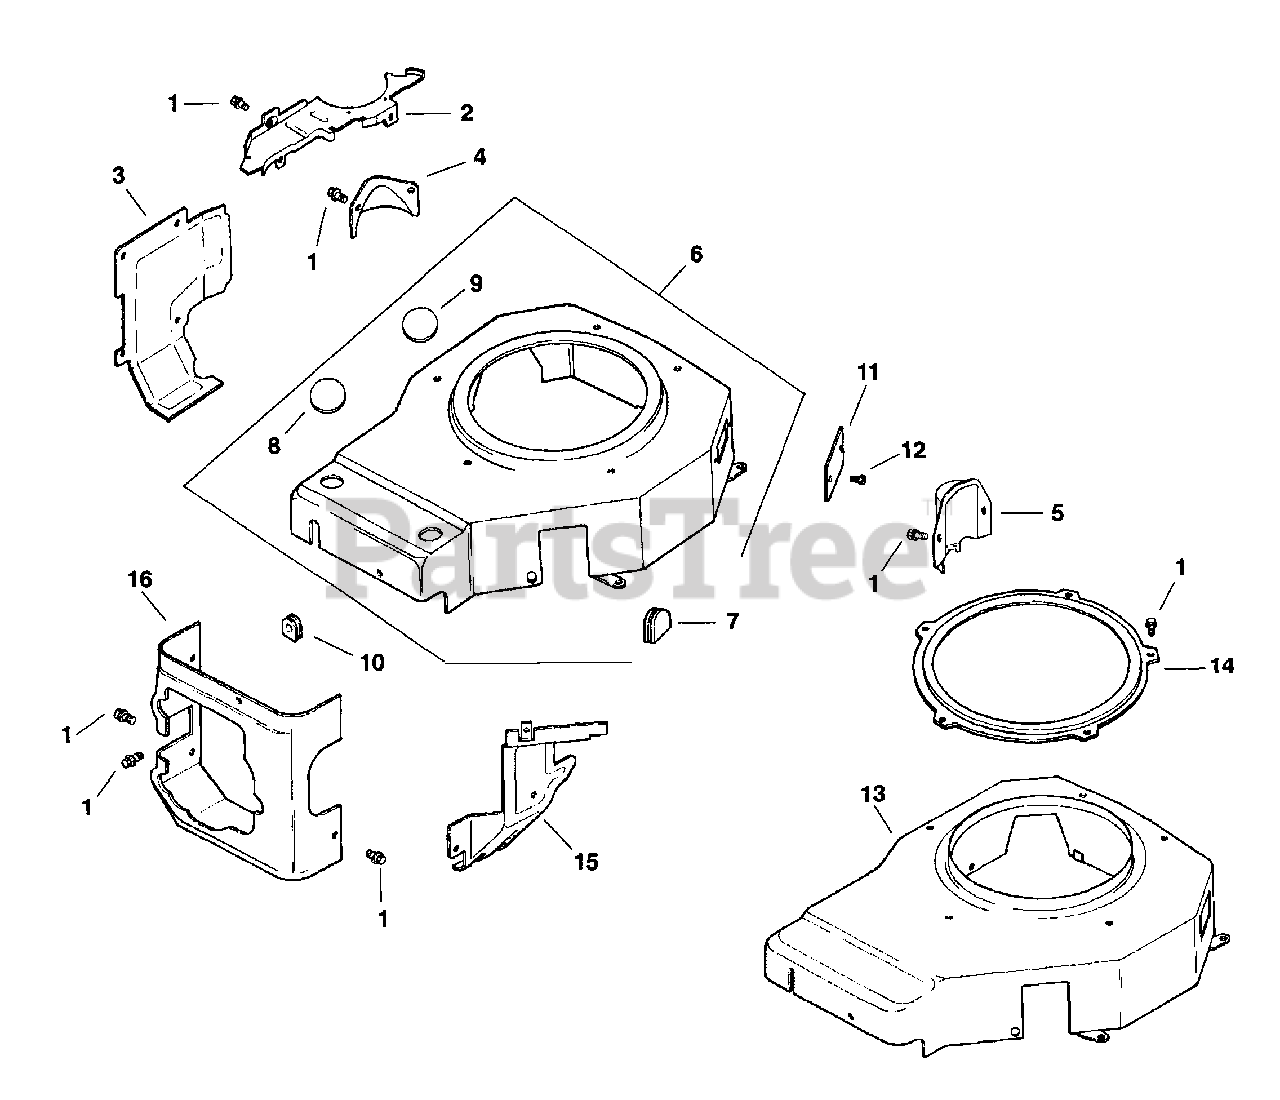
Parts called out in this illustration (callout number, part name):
1	SCREW - USE M-545010
2	PLATE, BACKING
5	COVER, STARTER -USE 12 096 39-S
6	HOUSING - USE 12 027 68
8	PLUG, BUTTON 9/16
9	PLUG, BUTTON 1/2
15	BAFFLE
16	BAFFLE - USE 12 063 08-S
